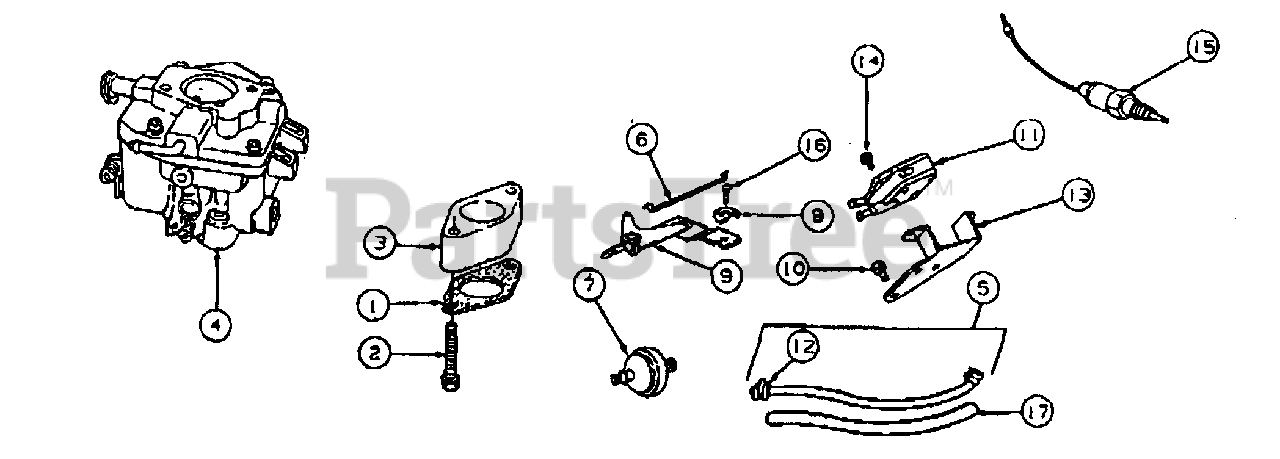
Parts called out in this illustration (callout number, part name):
1	Gasket, Carburetor Mtg
2	Screw, Sems
3	Spacer, Carburetor
4	Carburetor Assy
5	Line, Fuel
6	Link, Choke
7	Filter, Fuel,
8	Clamp, Casing
9	Bracket, Choke
10	Screw, Sems
11	Pump, Fuel
12	Clamp, Fuel Line
13	Bracket, Fuel Pump
14	Screw, Mtg
15	Solenoid
16	Screw, Max Hd
17	Insulation, Fuel Line
